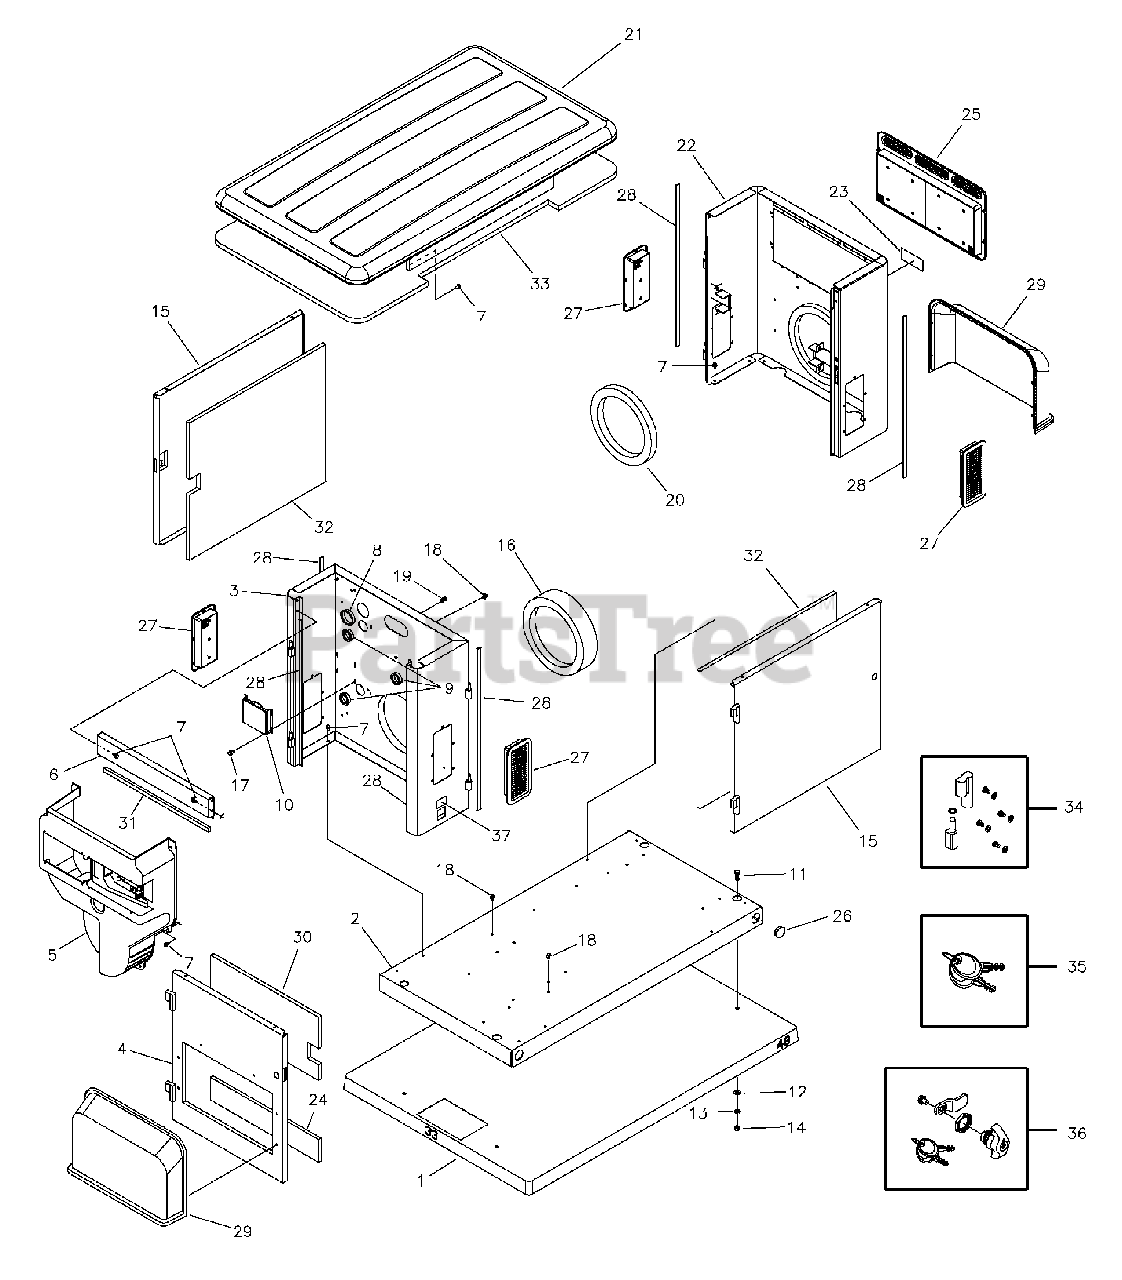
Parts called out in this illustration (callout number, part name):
1	PAD, Mounting w/ Holes
3	BULKHEAD, Engine
7	BOLT
9	BUSHING, Snap, 1-1/2
10	REGULATOR, Voltage
11	*CAPSCREW, Hex Head, 3/8-16 x 1
12	*WASHER, Flat, 3/8-M10
13	*WASHER, Lock, 3/8
14	*NUT, 3/8-16
16	SEAL, Foam, Engine Air
18	MOUNT, Tie Wrap
20	SEAL, Foam, Alternator Inlet
22	BULKHEAD, Alternator
24	INSULATION, Engine Door, Bottom
25	ASSEMBLY, Vent, Exhaust
29	COVER, Air Intake, Engine
30	INSULATION, Engine Door, Top
